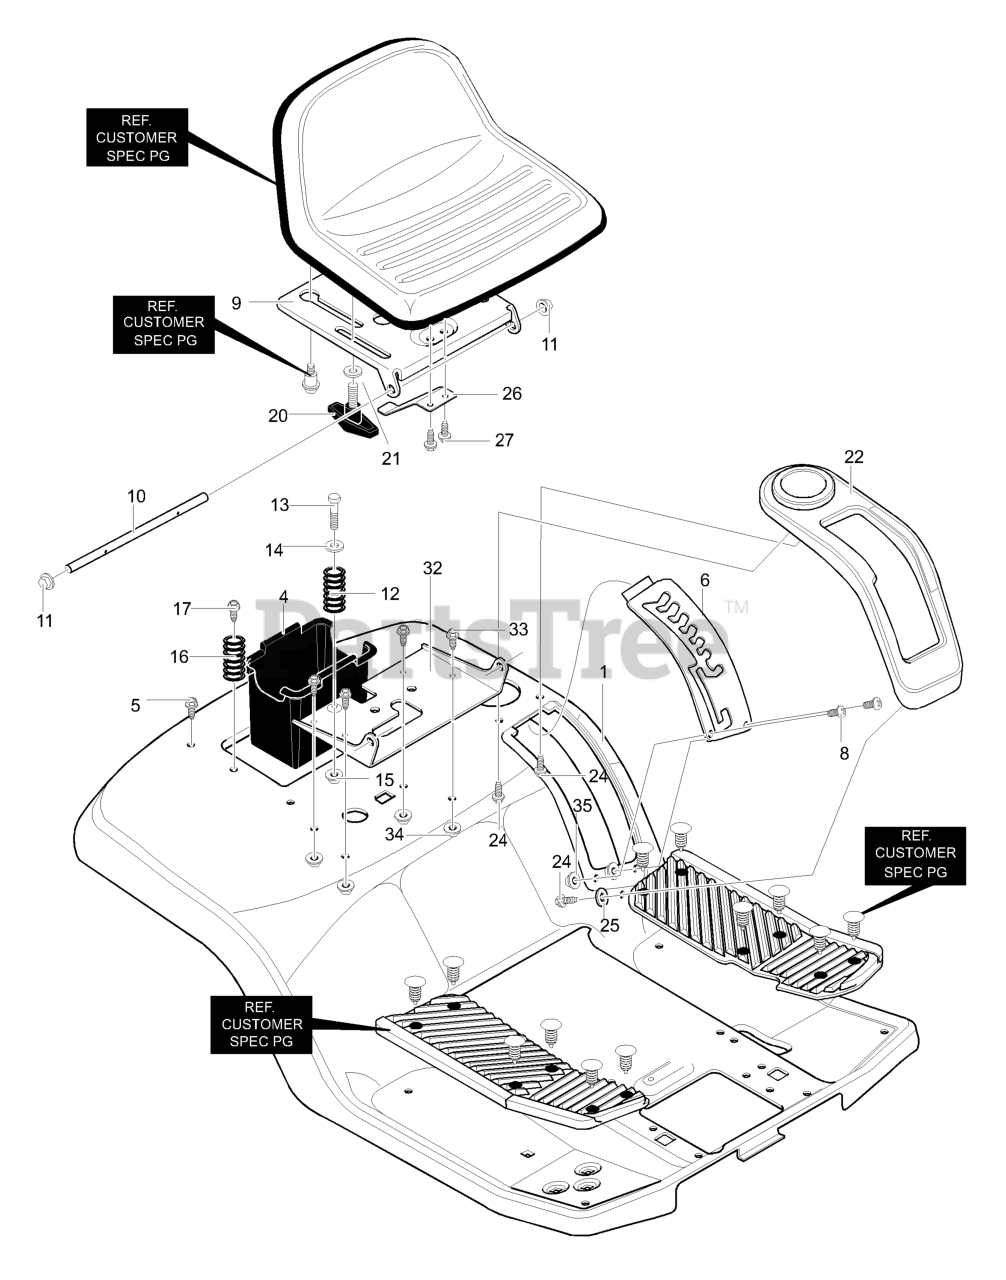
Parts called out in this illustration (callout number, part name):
1	Seat Deck
4	Battery Container
5	Screw, 1/4-20X.63
6	Plate, Lift Detent
8	Screw, 10-24x.500
9	Seat Support
10	Hinge Seat Pivot
11	Push Cap Nut
12	Comp. Spring
13	Shoulder Bolt, 1/4-20
14	Washer Cup
15	Nut, 1/4-20
16	Comp. Spring
17	Screw, 5/16-18 x 0.75
20	Wing Bolt 5/16-18X.50
21	Flat washer
22	Detent Cover w/cup
24	Screw, 1/4-15
25	Flat washer
26	Spring - Leaf
27	Screw, 1/4-20X.50
32	Pivot Seat Bracket
33	Screw, 5/16-18 x 0.75
34	Nut, 5/16-18 Wdfllk
35	Nut, #10-24 Locknut
